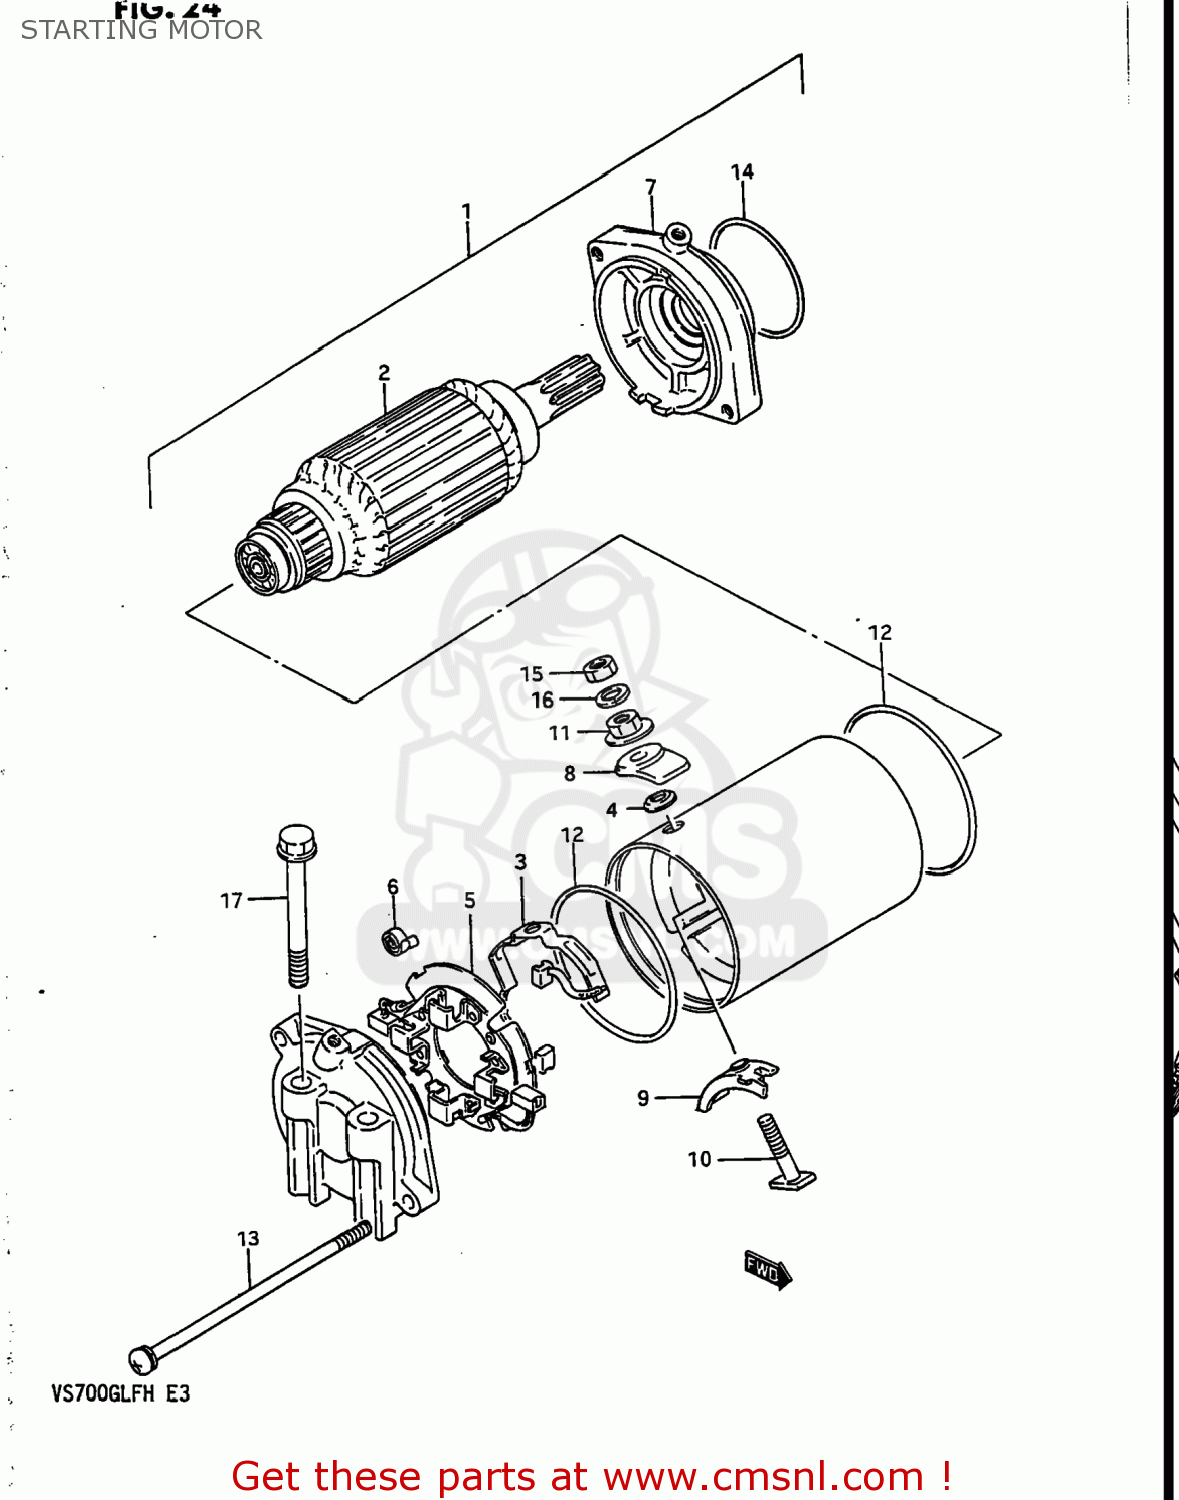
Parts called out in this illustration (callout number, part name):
1	MOTOR ASSEMBLY,STARTING
2	ARMATURE
3	TERMINAL SET,BRUSH
4	O RING
5	HOLDER SET,BRUSH (-)
6	SPRING
7	BRACKET SET
8	BUSHING
9	BUSHING
10	BOLT
11	NUT
12	O RING
13	BOLT
14	O RING
15	NUT
16	WASHER,LOCK
17	BOLT
